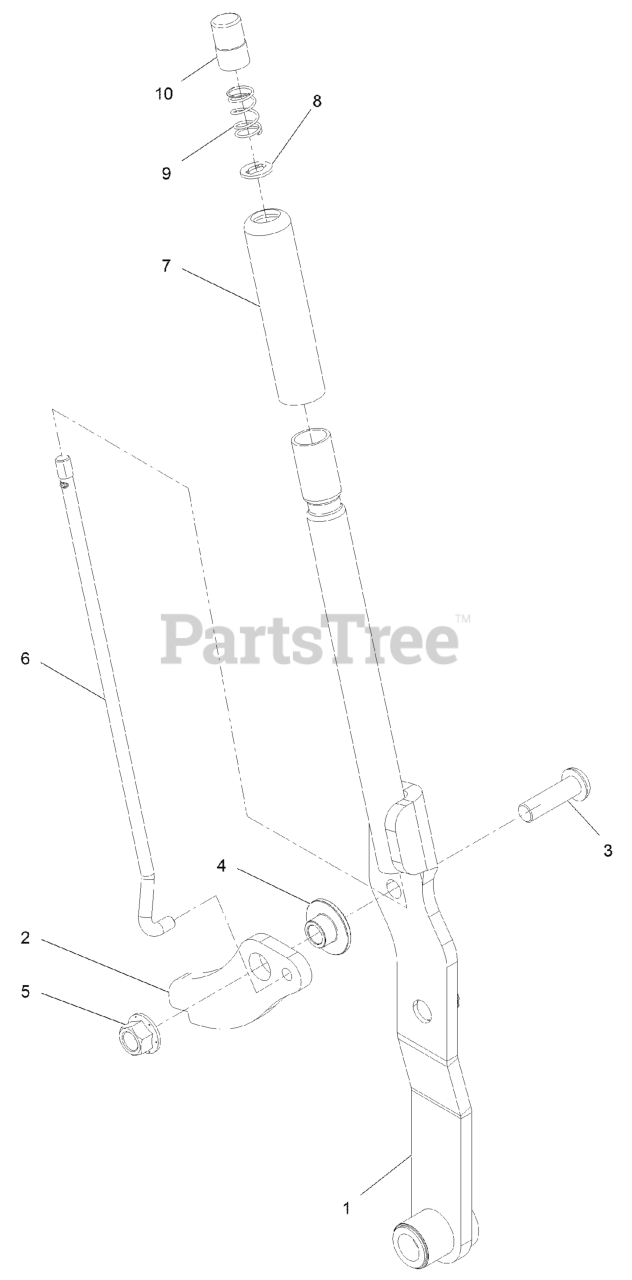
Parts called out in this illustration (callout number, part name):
1	ASM, HOC LEVER W/ BUSHINGS
2	ARM, TRANSPORT LOCK
3	SCREW-HSBH
5	Nut-Lock 1/2-13
6	LINC, HOC
8	WASHER-SPECIAL
9	SPRING-COMPRESSION
10	BUTTON, PUSH
